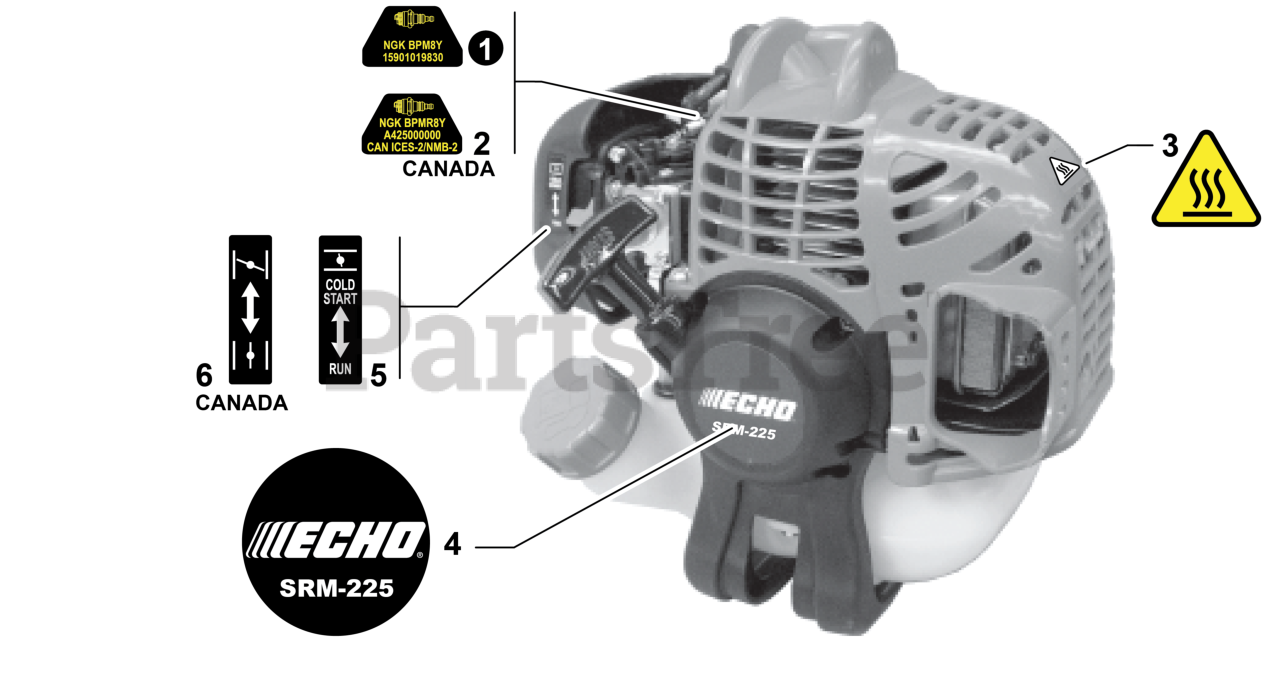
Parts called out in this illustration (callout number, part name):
1	LABEL - SPARK PLUG - BPM8Y
2	LABEL - SPARK PLUG - BPMR8Y
3	LABEL - CAUTION - HOT
4	LABEL - STARTER - SRM-225
5	LABEL - CHOKE
6	LABEL - CHOKE
